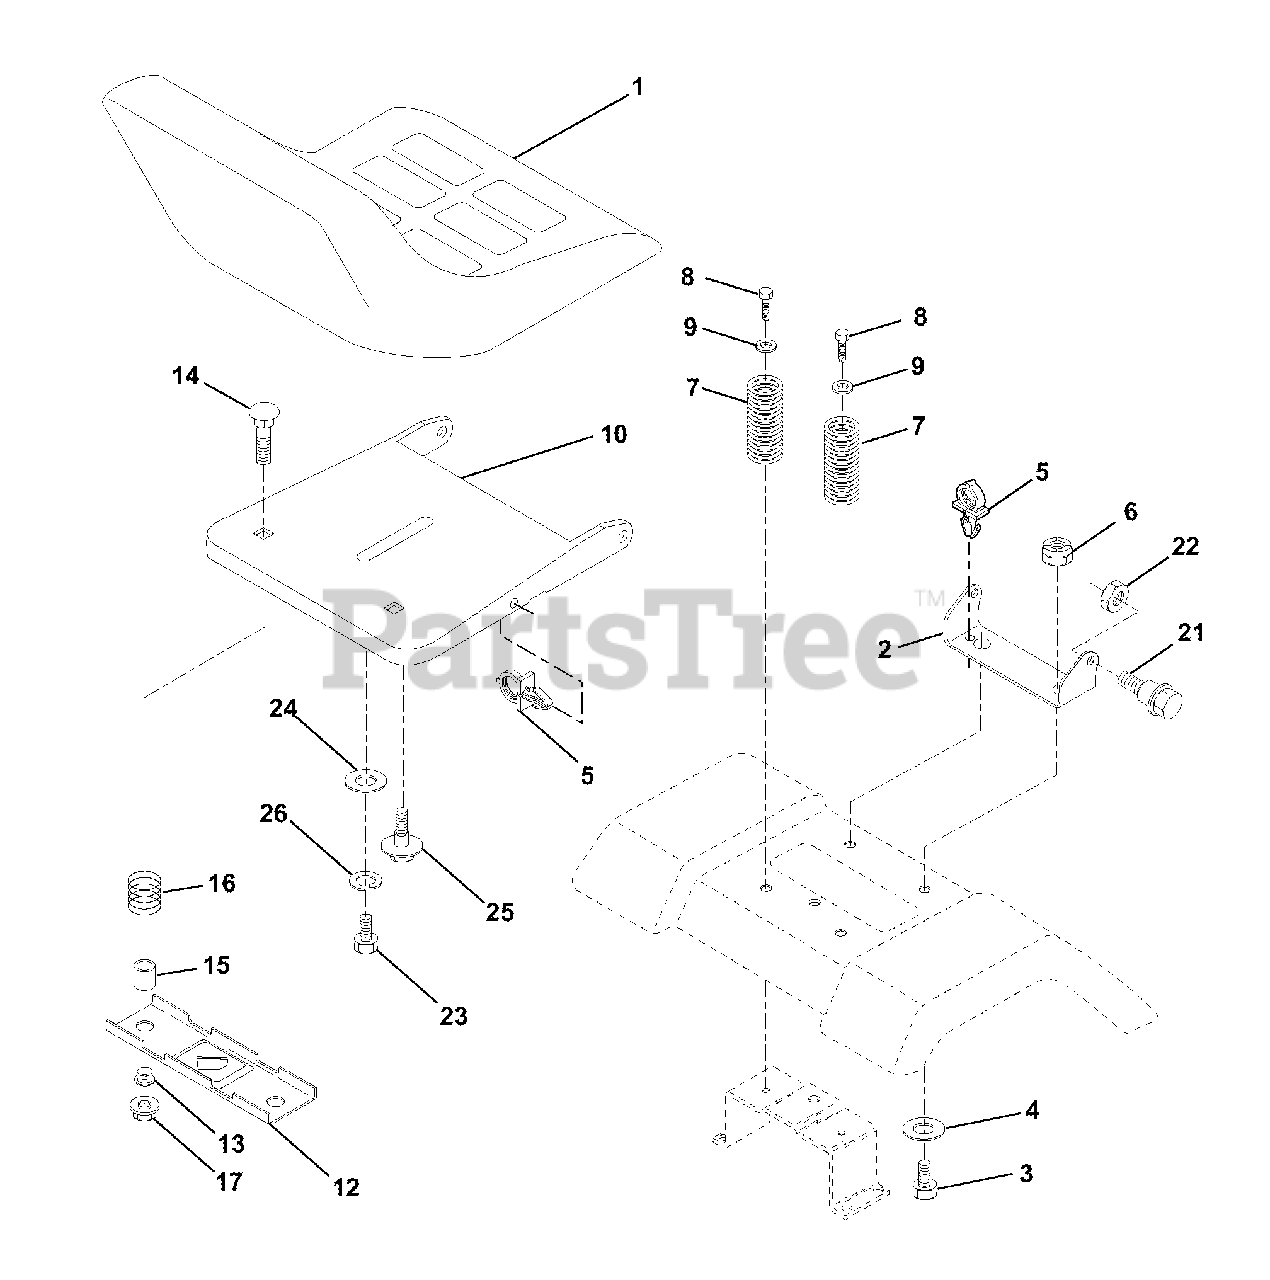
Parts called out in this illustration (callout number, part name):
1	Seat
2	Bracket Pnt Pivot Seat
3	Bolt
4	Washer 13/32 x 1 x 10 Ga
5	Clip Push-In Hinged
6	Nut
7	Spring Seat Cprsn 2 250 Blk Zi
8	Screw 3/8-16 x 1.5
9	Washer 13/32 x 1 x 14 Ga
10	Pan Pnt Seat (blk )
12	Bracket Pnt Mounting Switch
13	Bushing Snap Blk Nyl 50 Id
14	Bolt Rdhd Sht Nk 1/4-20 x 1-1/2
15	Spacer Split 28 x 96 Yel Zinc
16	Spring Cprsn 1 27 Blk Pnt
17	Nut Lock 1/4 Lge Flg Gr 5 Zinc
21	Bolt Shoulder 5/16-18 Unc Blkz-2A
22	Nut
23	Bolt Fin Hex 1/2-13 x 7/8 Gr 5
24	Washer 17/32 x 1-3/16 x 12 Ga
25	Bolt Shoulder 5/16-18 x 62
26	Lockwasher
